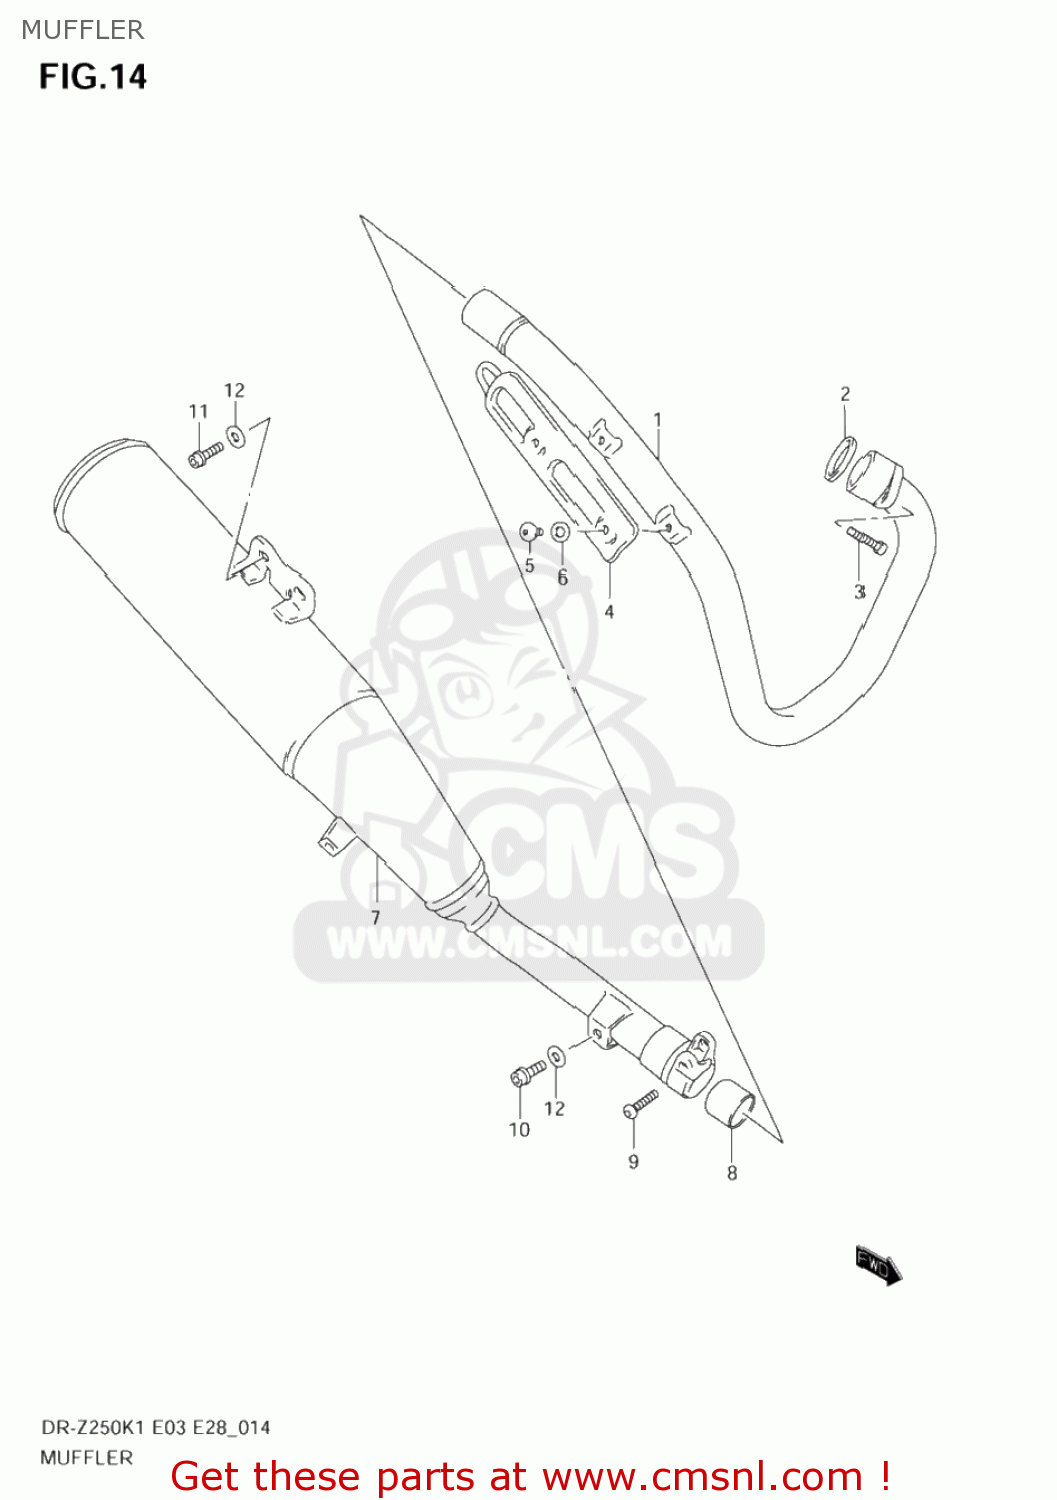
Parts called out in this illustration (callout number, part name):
1	PIPE,EXHAUST
2	GASKET,EXHAUST (NAS)
3	BOLT
4	COVER,EXHAUST PIPE
5	SCREW(6X10)
6	WASHER(6.5X13X1.0)
7	BODY,MUFFLER
8	CONNECTOR,MUFFLER
9	BOLT
10	BOLT(8X12)
11	BOLT(8X20)
12	WASHER (8.5X19X2.3)
